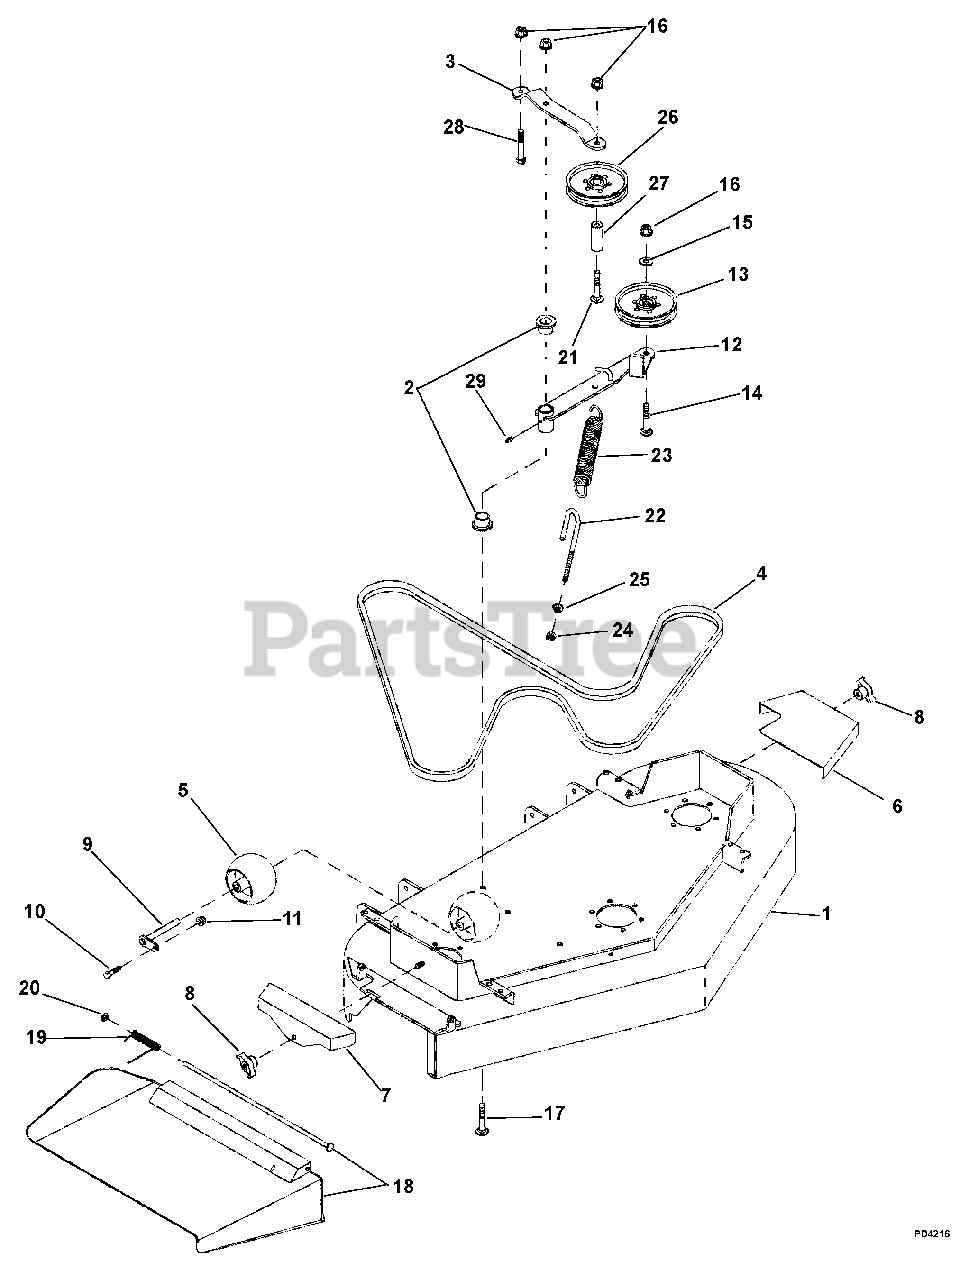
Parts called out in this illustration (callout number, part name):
1	Mower Deck (994100)
2	Bushing
3	Strap, Idler Pulley
4	Belt, Engine-to-Blades (994100)
5	Wheel, Gage
6	Belt Cover, LH
7	Belt Cover, RH (994100)
8	Knob, 3/8-16 Insert
9	Pivot, Anti-Scalp Roller
10	Bolt, Round Head Square Neck .25-20 x 1.00
11	Nut, 1/4" Flange Prevailing Torque
12	Arm, Idler Engine-to-Blade
13	Pulley, Flat Tension Idler
14	Bolt, Round Head Square Neck .38-16 x 2.25
15	Washer, Flat, Steel .406 x .812 x .065
16	Nut, Locking, Center, .38-16
17	Bolt, 3/8-16 x 4.00
18	Discharge Chute (994100)
19	Spring, Torsional Discharge
20	Clip, Retainer
21	Bolt, 3/8-16 x 3-3/4
22	J-Hook
23	Spring, Deck Belt Tension
24	Nut, Lock, Nylon .38-16
25	Nut, Flange .375-16
26	Pulley, Flat Blade-to-Blade
27	Spacer, Blade-to-Blade Pulley
28	Bolt, Round Head Square Neck .38-15 x 1.25
29	Fitting, Lubrication
